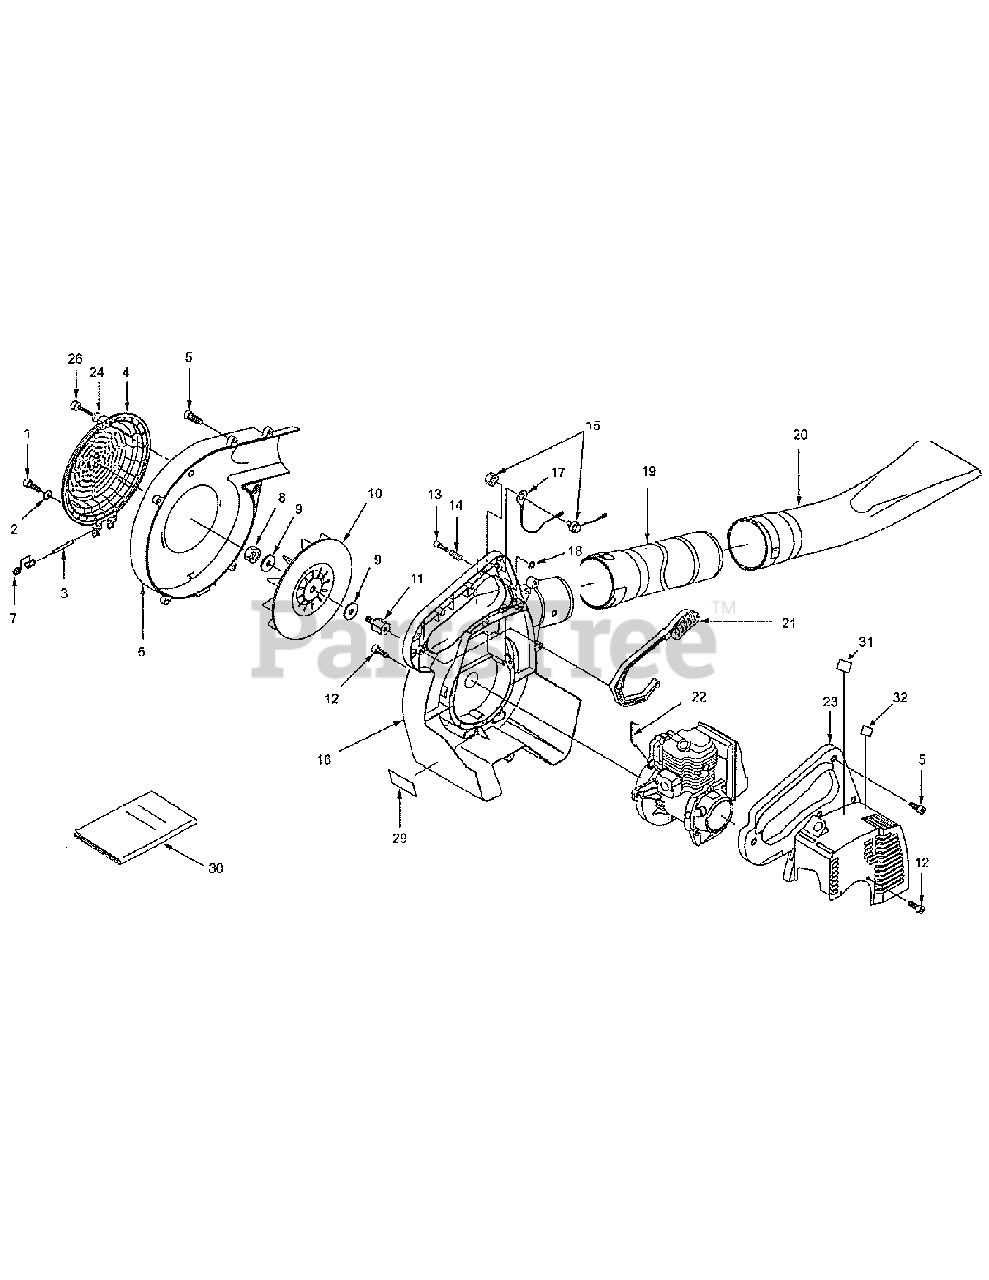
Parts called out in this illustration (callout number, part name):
1	Bolt, M5x14
5	Bolt, PC5x18
13	Lever, Throttle
14	Spring, Throttle
15	Switch, Stop
17	Harness, Wire
18	Snap Ring, E-3
19	Pipe, Straight
20	Pipe, Tail
21	Lever, Throttle
22	Lever, Throttle
23	Cowling, Cylinder
29	Caution Plate
30	Manual, Operator's
32	Caution Plate
